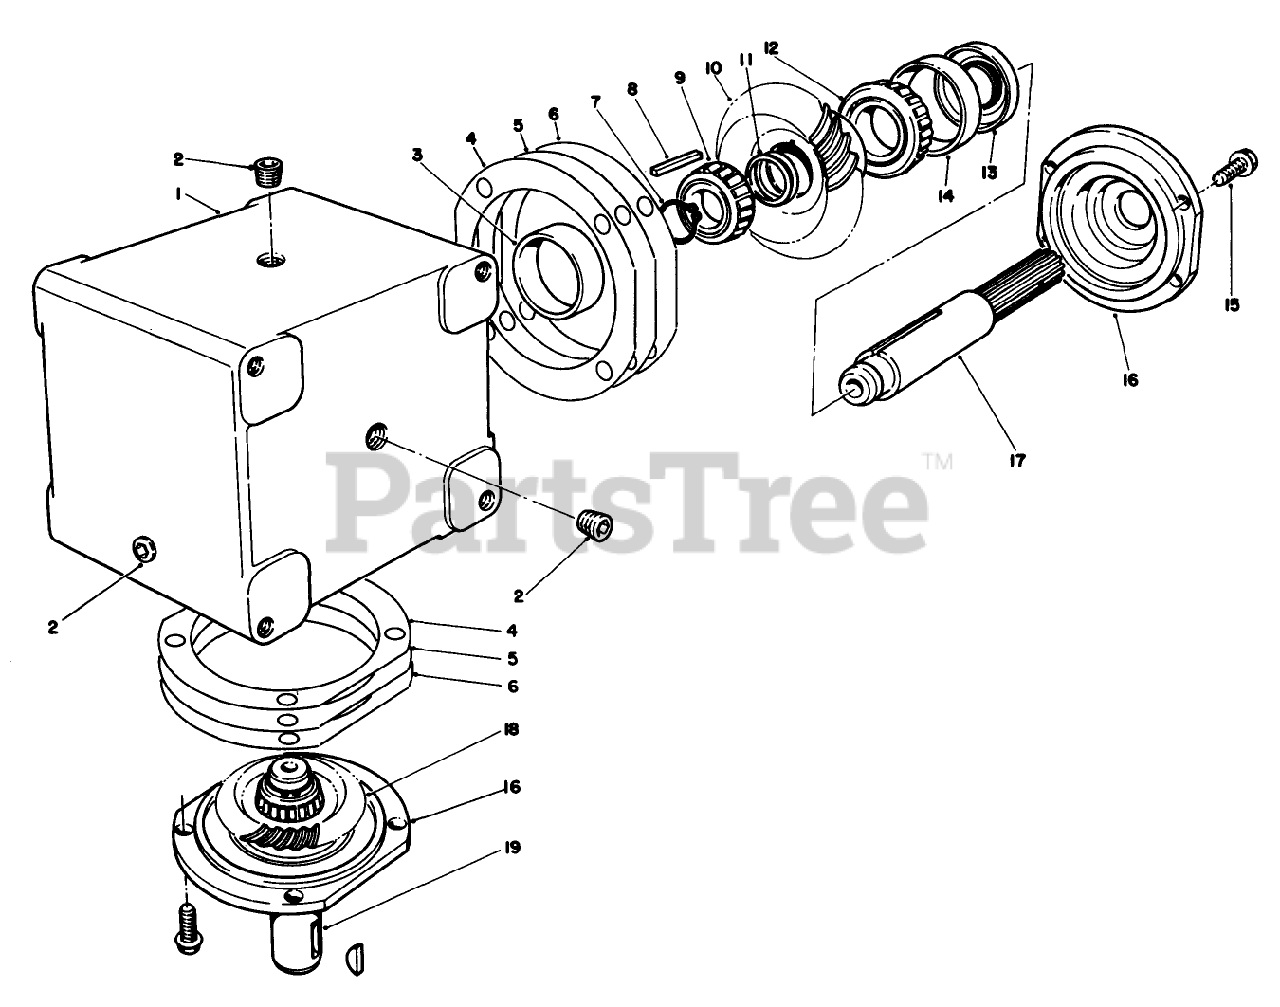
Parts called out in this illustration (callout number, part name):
1	HOUSING
2	PLUG (OBS, C/R TO 281-10)
3	Bearing Cup
4	GASKET
5	GASKET
6	GASKET
7	Ring-Retaining
8	Key
9	Cone
12	Cone
13	Seal
14	Cup
15	SCREW-HH (OBS, C/R TO 3234-5)
17	Shaft
19	Shaft
